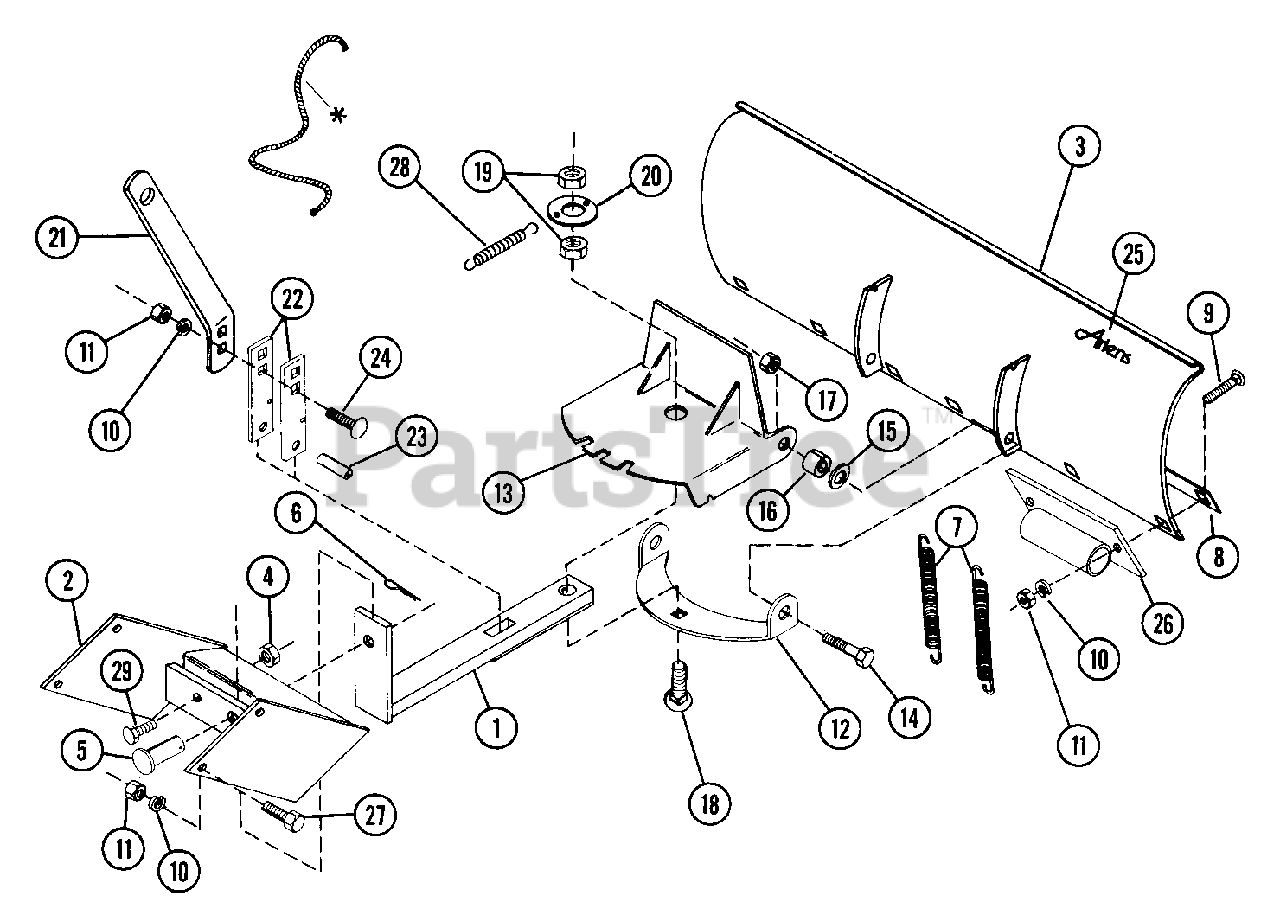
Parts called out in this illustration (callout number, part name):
1	DOZER BLADE FRAME
2	40 INCH SNOW BLADE
3	PUSH TUBE ASSEMBLY
4	NUT-LK-CTR .375-16 GR A PL
5	CLEVIS PIN
6	CONDUIT NUT
7	SG-TENS .125X.81X6.50 WLD 10
8	WEAR BAR
9	BLT-RDHDSQSHNK .38-16X1.00 PL
10	WSHR-LK .375X.115 HVY PL
11	NUT-HEX .375-16
12	LOWER PIVOT PLATE
13	UPPER PIVOT PLATE
14	BLT-HEX .50-13X1.50 PL GR2
15	WSHR-FL-STL .531X1.062X.095 PL
16	PIVOT BUSHING
17	NUT-LK-CTR .50-13
18	BLT-RDHDSQNK .75-10X3.0
19	NUT-JAM .75-10 PL
20	LATCH SPRING WASHER
21	PIVOT BLOCK EXTENSION
22	BAR PIVOT LOCK
23	PIN-ROLL .250X1.00
24	BLT-RDHDSQNK .38-16X1.25 PL
25	ARIENS SCRIPT DECAL
27	BLT-HEX .38-16X1.00 PL
28	SG-TENS .106X.56X2.75 WLD 10
29	BLT-HEX .38-16X1.50 PL GR2
